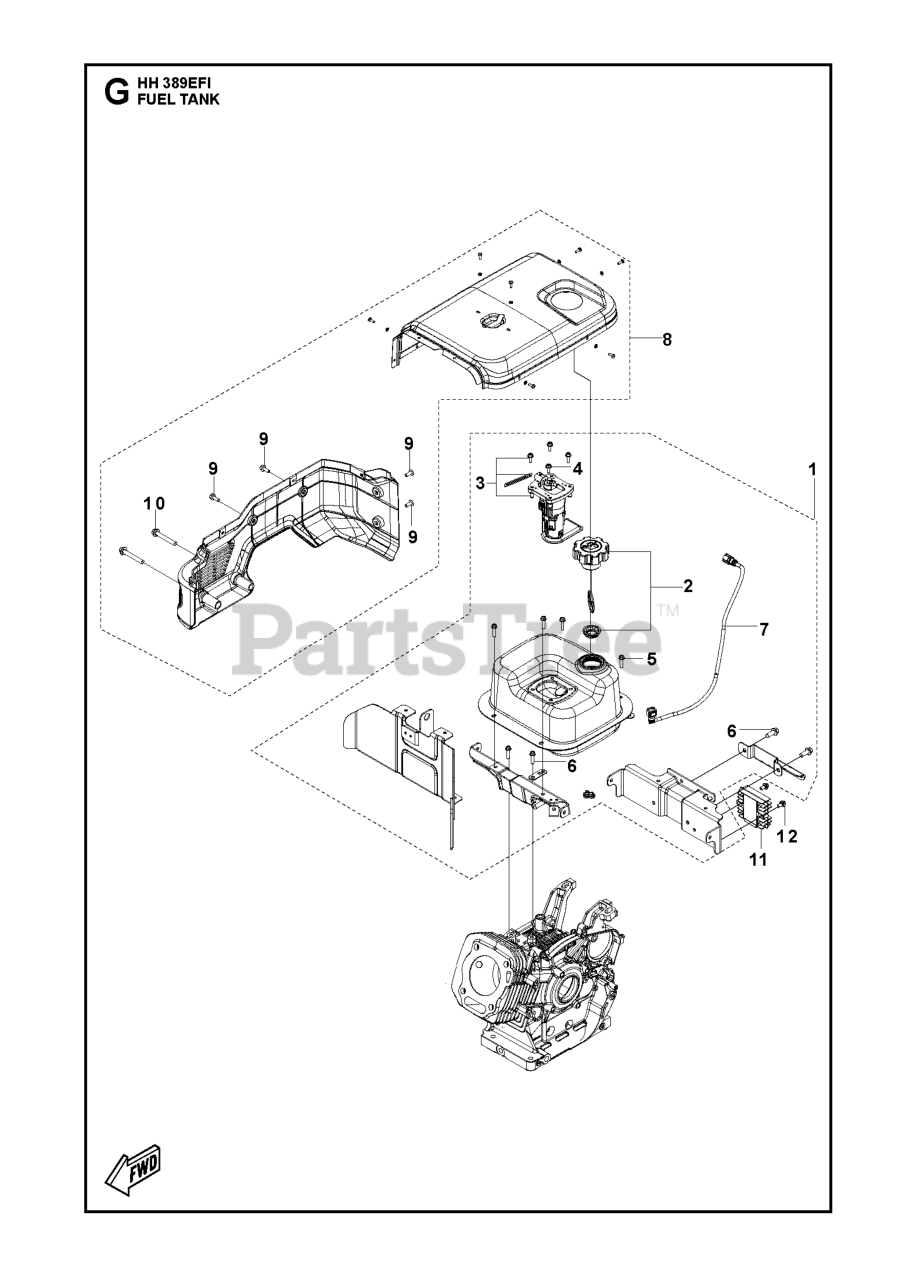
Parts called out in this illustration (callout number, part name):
1	FUEL TANK ASSY
2	FUEL CAP ASSY
3	FUEL PUMP FUEL PUMP ASSY
4	BOLT
5	BOLT
6	BOLT
7	TUBE FUEL TUBE
8	COVER KIT FUEL TANK COVER KIT
9	BOLT
10	BOLT
11	REGULATOR VOLTAGE REGULATOR
12	BOLT
